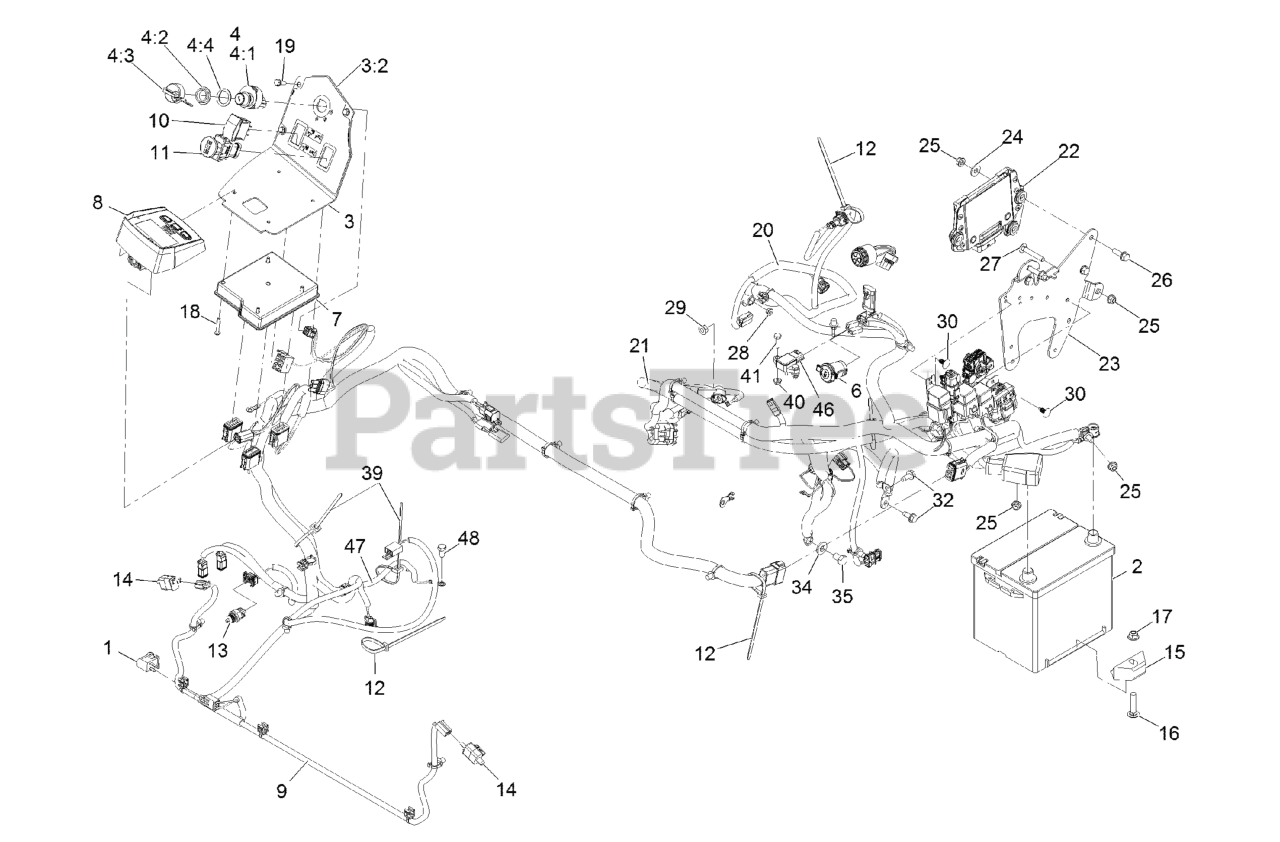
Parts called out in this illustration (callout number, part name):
1	SWITCH-BAIL
2	Battery-Dry
3	Console ASM
3:2	DECAL-CONTROL PANEL
4	IGNITION SWITCH ASM
4:1	Switch-Ignition
4:2	NUT-MOUNTING
4:3	IGNITION KEY SET
4:4	WASHER-BACKUP
6	PORT-POWER, 12V
7	Module-Mcu
8	Module, Ldu
9	HARNESS-WIRE
11	SWITCH-PTO, SEALED
12	TIE-PLASTIC
13	SENSOR-TEMPERATURE
15	RETAINER-BATTERY
16	SCREW-CARR
17	NUT-HF, NI
18	SCREW-PPH
19	SCREW-HWH
20	HARNESS-WIRE
21	CABLE-BATTERY
22	ECU ASM
23	BRACKET-MOUNT, ECU
24	WASHER-FLAT
25	NUT-HF, NI
26	SCREW-HHF
27	BOLT-CARR
30	PLUG-PLASTIC
32	Screw-HWH 5/16-18 X 3/4 Tf
34	WASHER-BELLEVILLE
35	SCREW-HH
39	TIE-CABLE
41	SCREW-HH
46	SENSOR-ATM
47	HARNESS-WIRE, JUMPER
48	BOLT
